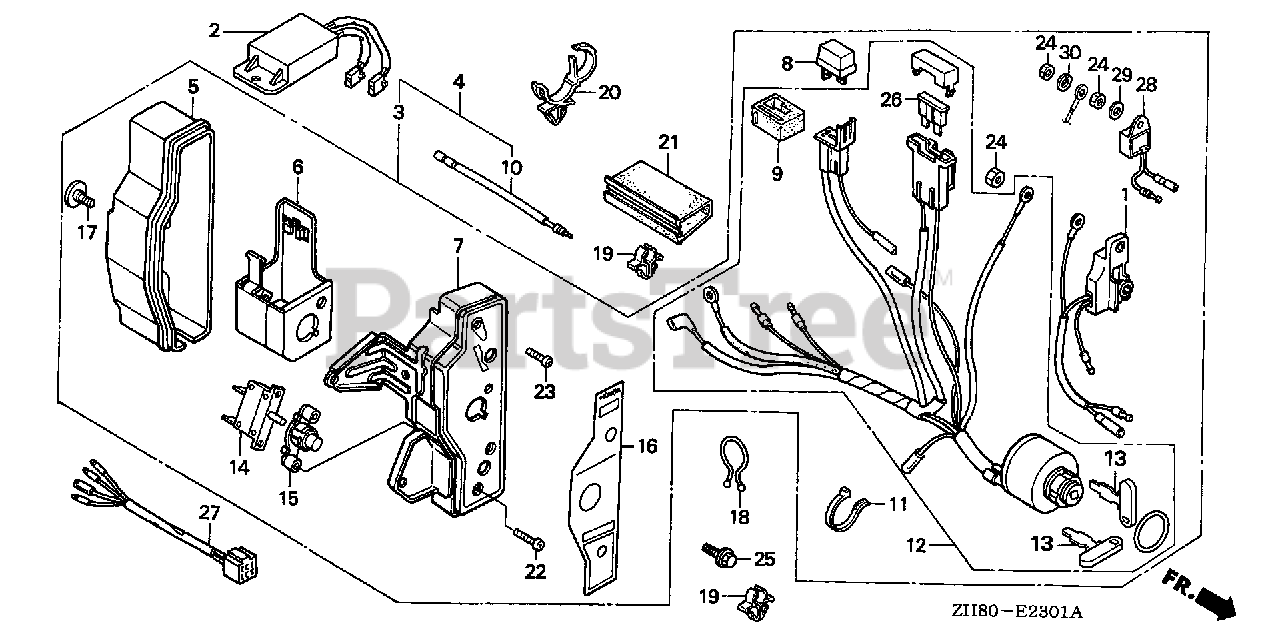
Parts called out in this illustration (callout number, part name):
1	ALERT UNIT, OIL
3	BOX ASSY., CONTROL *R8* (EXP-ALERT) (BRIGHT RED)
4	BOX ASSY., CONTROL *R280* (EXP-ALERT) (POWER RED)
5	CASE, CONTROL
6	BRACKET, CASE MOUNTING
7	PANEL, CONTROL *R280* (POWER RED)
8	RECTIFIER ASSY., SILICON (SHINDENGEN)
9	SUSPENSION, CONNECTOR
10	SUB-WIRE HARNESS
11	BAND
12	SWITCH ASSY., COMBINATION
13	KEY (HONDALOCK)
14	PROTECTOR, CIRCUIT (1.0A)
15	LENS ASSY., PROTECTOR
16	MARK, CONTROL BOX (EXP)
16	PANEL, CONTROL BOX (EXTERNAL-ALERT) (NOT AVAILABLE)
17	SCREW, SPECIAL (6X12)
18	CLIP, PURSE LOCK
19	CLIP, CORD
20	STRAP, WIRE HARNESS (25MM) (BLACK)
21	TUBE, FASTENER (30MM)
22	SCREW, PAN (3X12)
23	SCREW, PAN (4X12)
24	NUT, HEX. (4MM)
25	BOLT, FLANGE (6X10)
26	FUSE, BLADE (5A)
28	ALERT UNIT, OIL
29	WASHER, PLAIN (4MM)
30	WASHER, SPRING (4MM)
